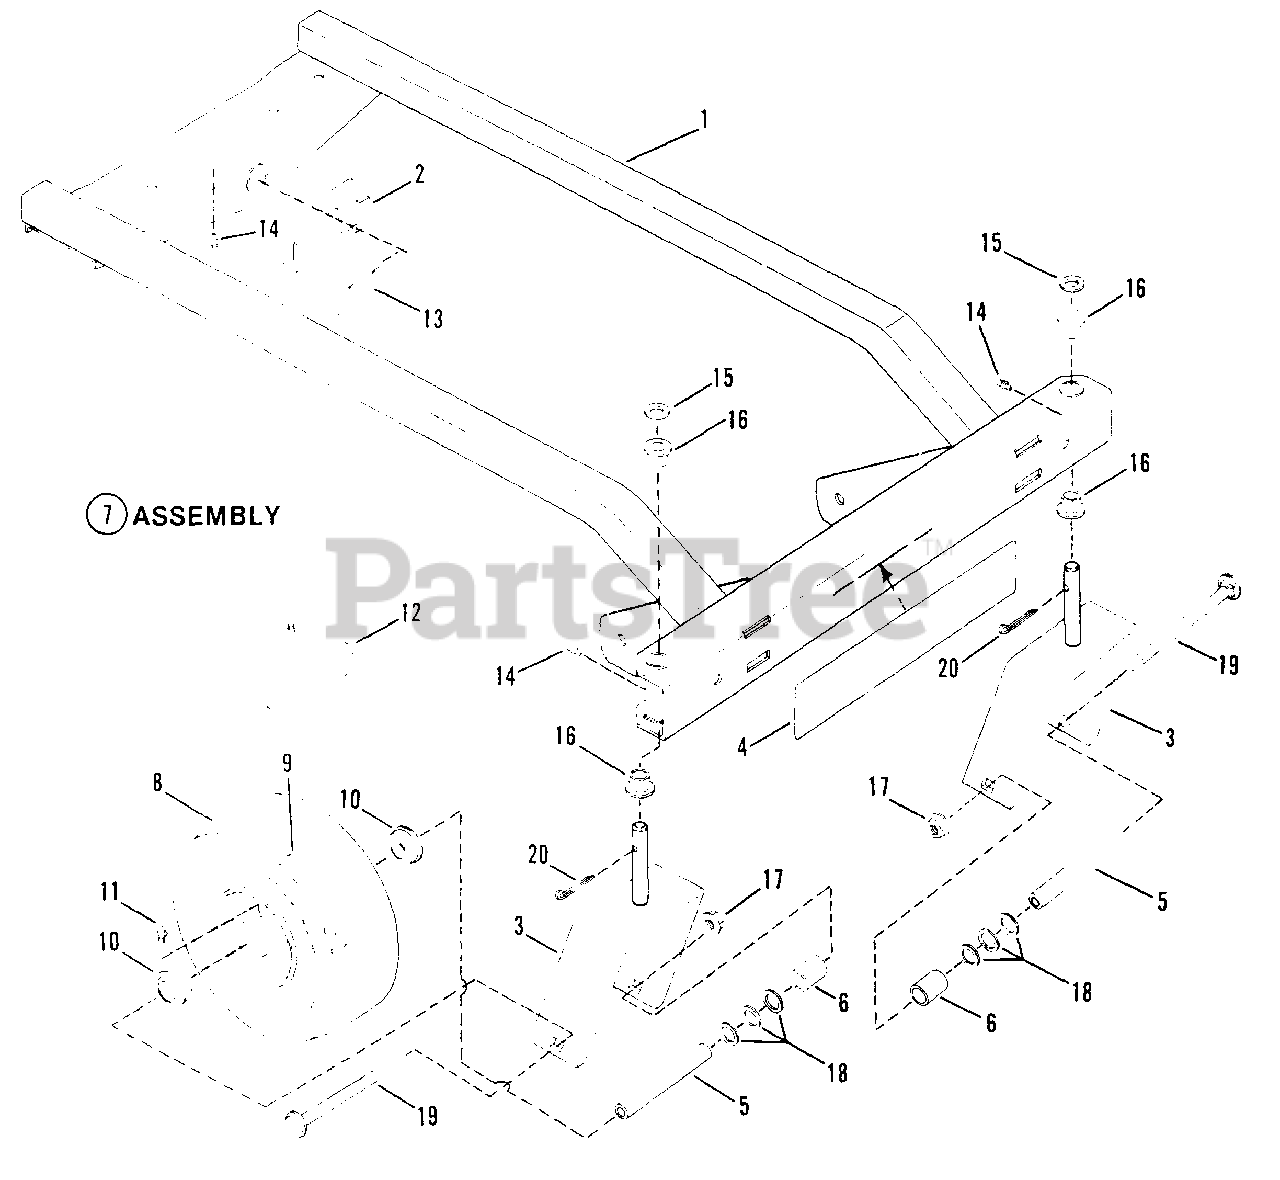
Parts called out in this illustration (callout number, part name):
1	FRAME, Front
3	CASTER
4	DECAL-SNAPPER
5	TUBE, Caster
6	SPACER, Axle 1.00 OD X .758 ID X 1.00 L
7	ASSEMBLY, Tire & Rim
8	TIRE, 4.10/3.50 x 4
9	RIM, (For 4.10/3.50x4 Tire)
10	BEARING, Ball
11	FITTING, Lube
12	TUBE, Inner
13	PIN, Hair
14	FITTING, Lube
15	WASHER, Flat, 3/4"
16	BUSHING
17	NUT, 1/2-13 Hex Flange Lock
18	WASHER
19	BOLT, 1/2-13 x 5-1/2" SSNC
20	COTTER-PIN, 5/32 x 1"
